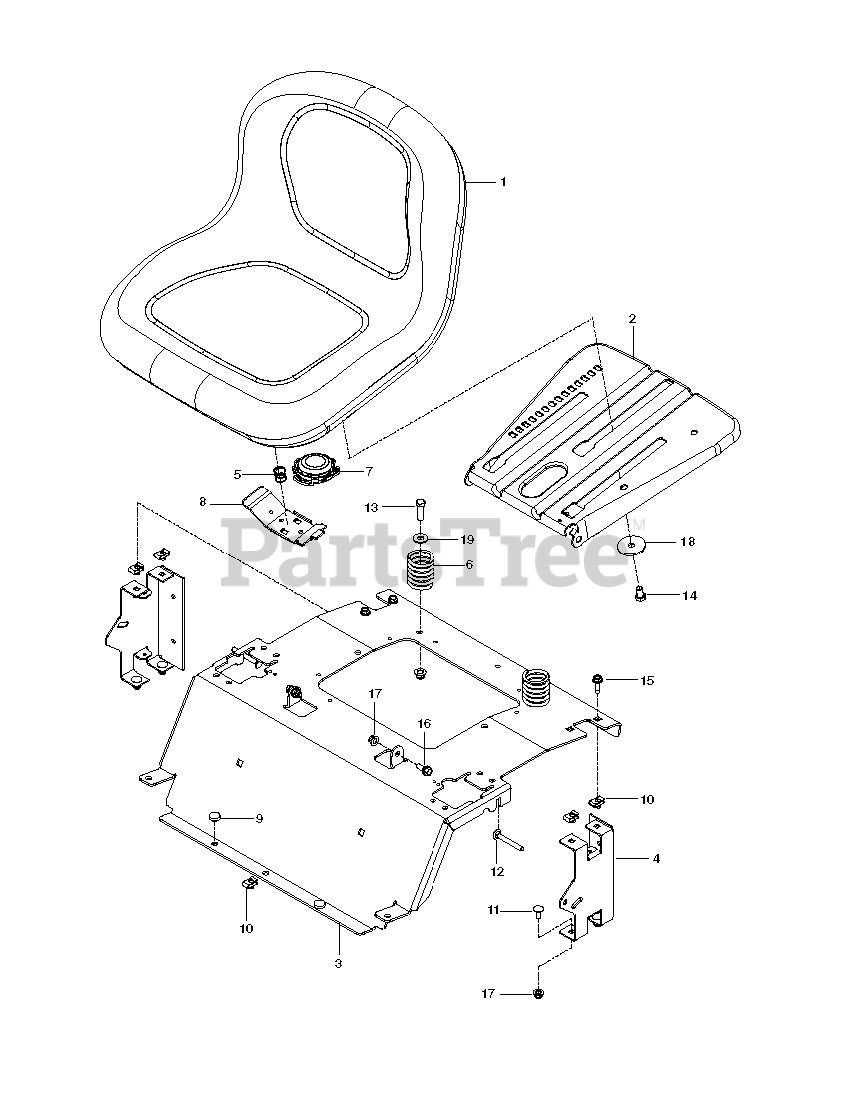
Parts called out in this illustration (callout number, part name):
1	SEAT.TH150.MS498.GRY.HUSQ.TEX
2	PAN.ASM.SEAT.3PT
3	SUPPORT SEAT ORANGE
4	SUPPORT REAR SEAT BLACK
5	SPRING.LATCH.SEAT.TEX
6	SPRING, SEAT
7	SWITCH, SEAT N/C
8	HANDLE.SLIDE.SEAT.TEX.BLACK
9	GROMMET, BUMPER
10	U-CLIP 5/16-18 NUT RETAINER
11	BOLT 5/16C X 3/4" CARRIAGE
12	RHSNB 5/16-18 X 2-1/2 GR5 ZD
13	HCS 3/8C X 1 1/4 GR5
14	HCS 3/8-16 X 5/8 GR 5 ZD
15	SCREW.THDROL.5/16-18X3/4.TTY
16	BOLT, SHOULDER
17	5/16-18 NYLOC FLANGE NUT
18	WASHER, 3/8 SPEC
19	WASHER 3/8 FLAT
